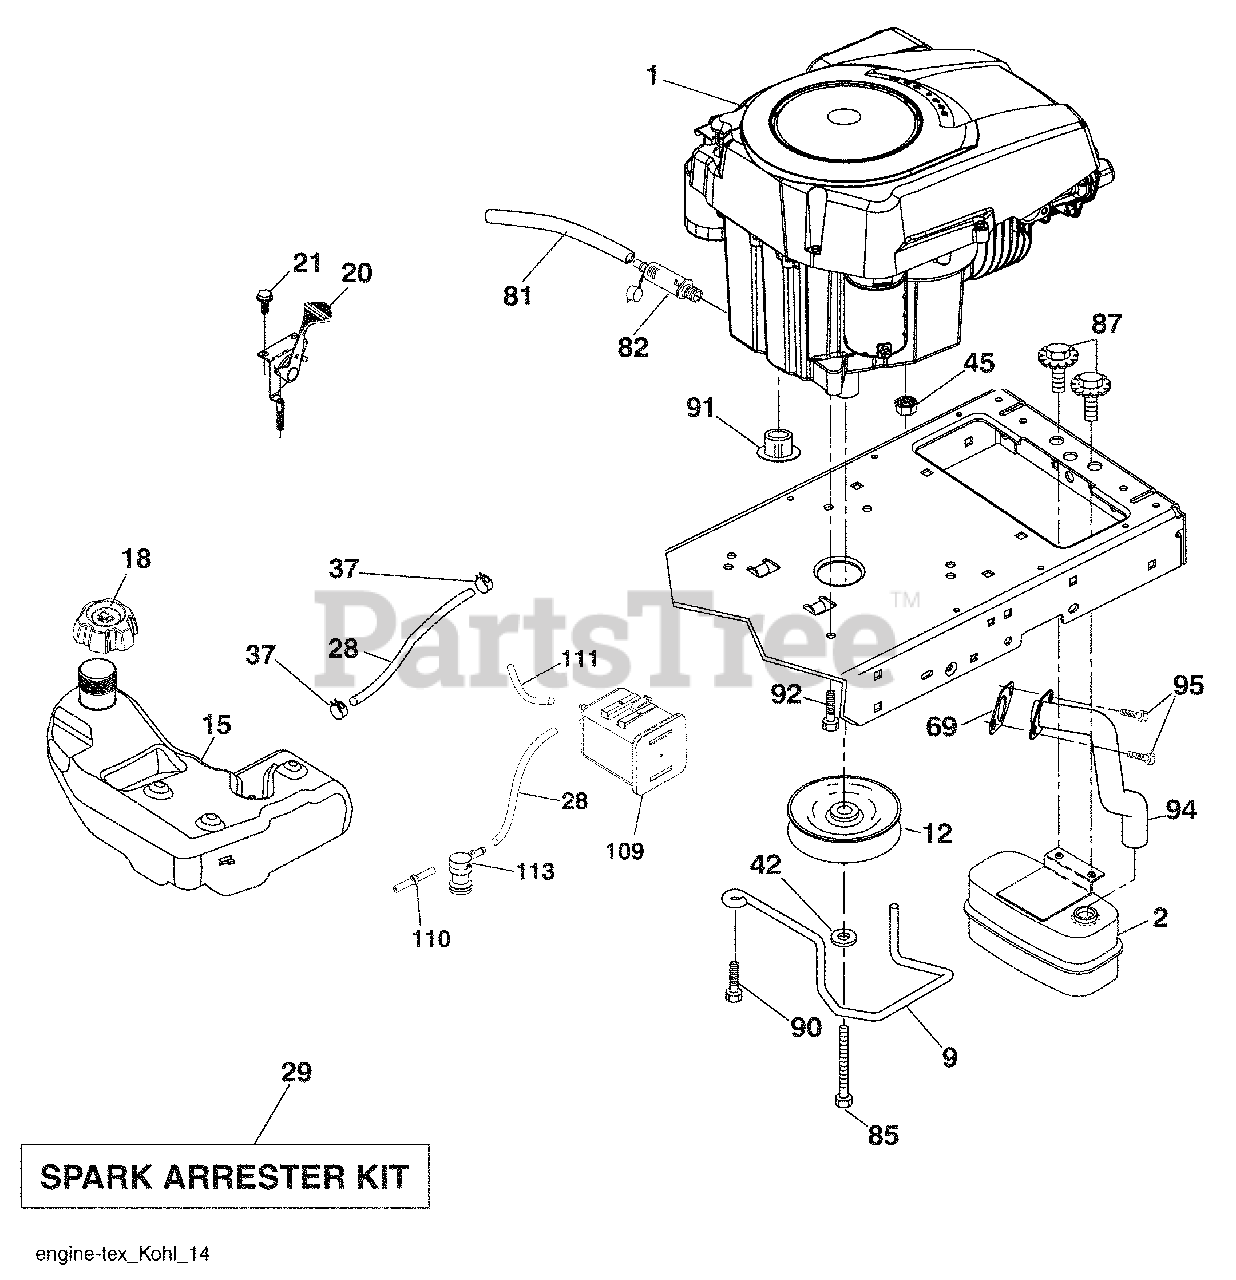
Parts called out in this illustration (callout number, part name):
9	Keeper Belt Engine
12	Pulley Engine
18	Cap Asm
20	Control Throttle
21	Screw # 10 x 0.750
28	Fuel Line
29	Spark Arrester Kit
37	Clamp Hose
42	Washer Lock 7/16
45	Nut Keps Hex 1/4-20 unc
81	Tube Drain Oil Easy
82	Plug Drain Oil
85	Bolt Hex 7/16-20 x 4 x Gr. 5-1.5 Thr
87	Bolt 5/16-18 unc x 3/4 w/Sems
90	Screw 3/8-16 x 1
92	Screw 3/8-16 x 1
94	Tube Exhaust
95	Screw Socket Hd. 5/16-18 x .75
96	Washer 9/32 x 7/8 x 16 Ga.
97	Screw 1/4-20 x 3/4
109	Canister Carbon Filter Asm.
110	Valve Anti-Slosh
111	Purge Line
113	Valve Slant Cartridge
